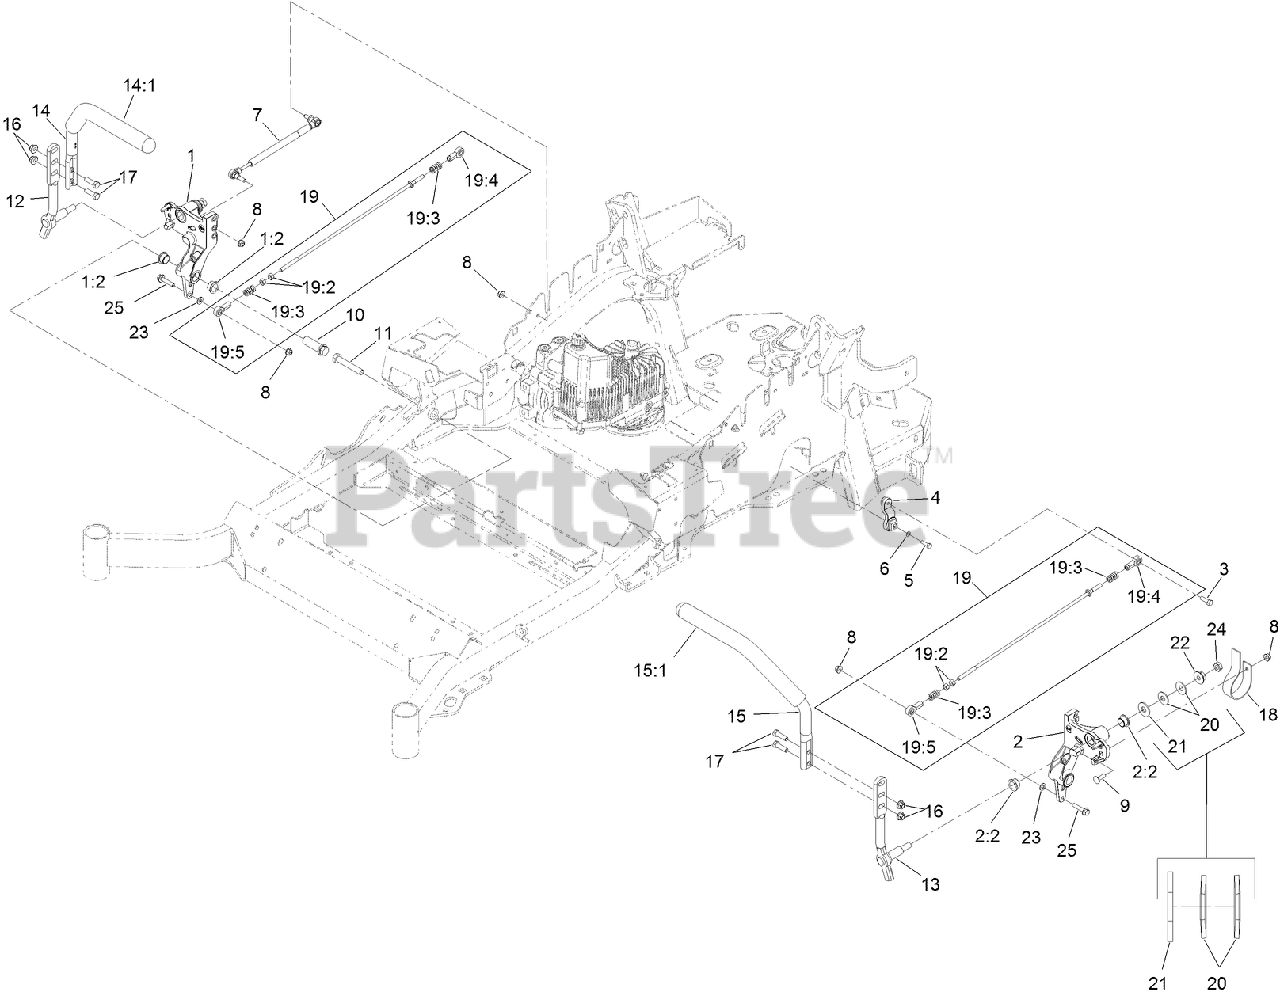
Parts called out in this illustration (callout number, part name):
1	RH MOTION CONTROL AND BUSHING ASM
1:2	BUSHING-FLANGE
2	LH MOTION CONTROL AND BUSHING ASM
2:2	BUSHING-FLANGE
3	SCREW-HH, THREAD LOCKING
4	ARM-CONTROL, PUMP
5	SCREW-HH
6	WASHER-SPRING
7	DAMPER-CONTROL, MOTION
8	NUT-HF, NI
9	BOLT-CARR
10	HUB-THREADED
11	SCREW-HH
12	LEVER-CONTROL MOTION, RH
13	LEVER-CONTROL MOTION, LH
14	RH STEERING HANDLE ASM
14:1	GRIP-CONTROL, LEVER
15	LH STEERING HANDLE ASM
15:1	GRIP-CONTROL, LEVER
16	NUT-HF, NI
17	SCREW-HH
18	SPRING-LEAF
19	PUMP LINKAGE REAR ASM
19:2	NUT-HEX
19:3	SPRING-COMPRESSION
19:4	BALLJOINT-LH
19:5	BALLJOINT-RH
20	WASHER-SPRING
21	WASHER-FLAT
22	NUT-HF
23	WASHER-PLAIN
24	NUT-JAM
25	SCREW-HHF
